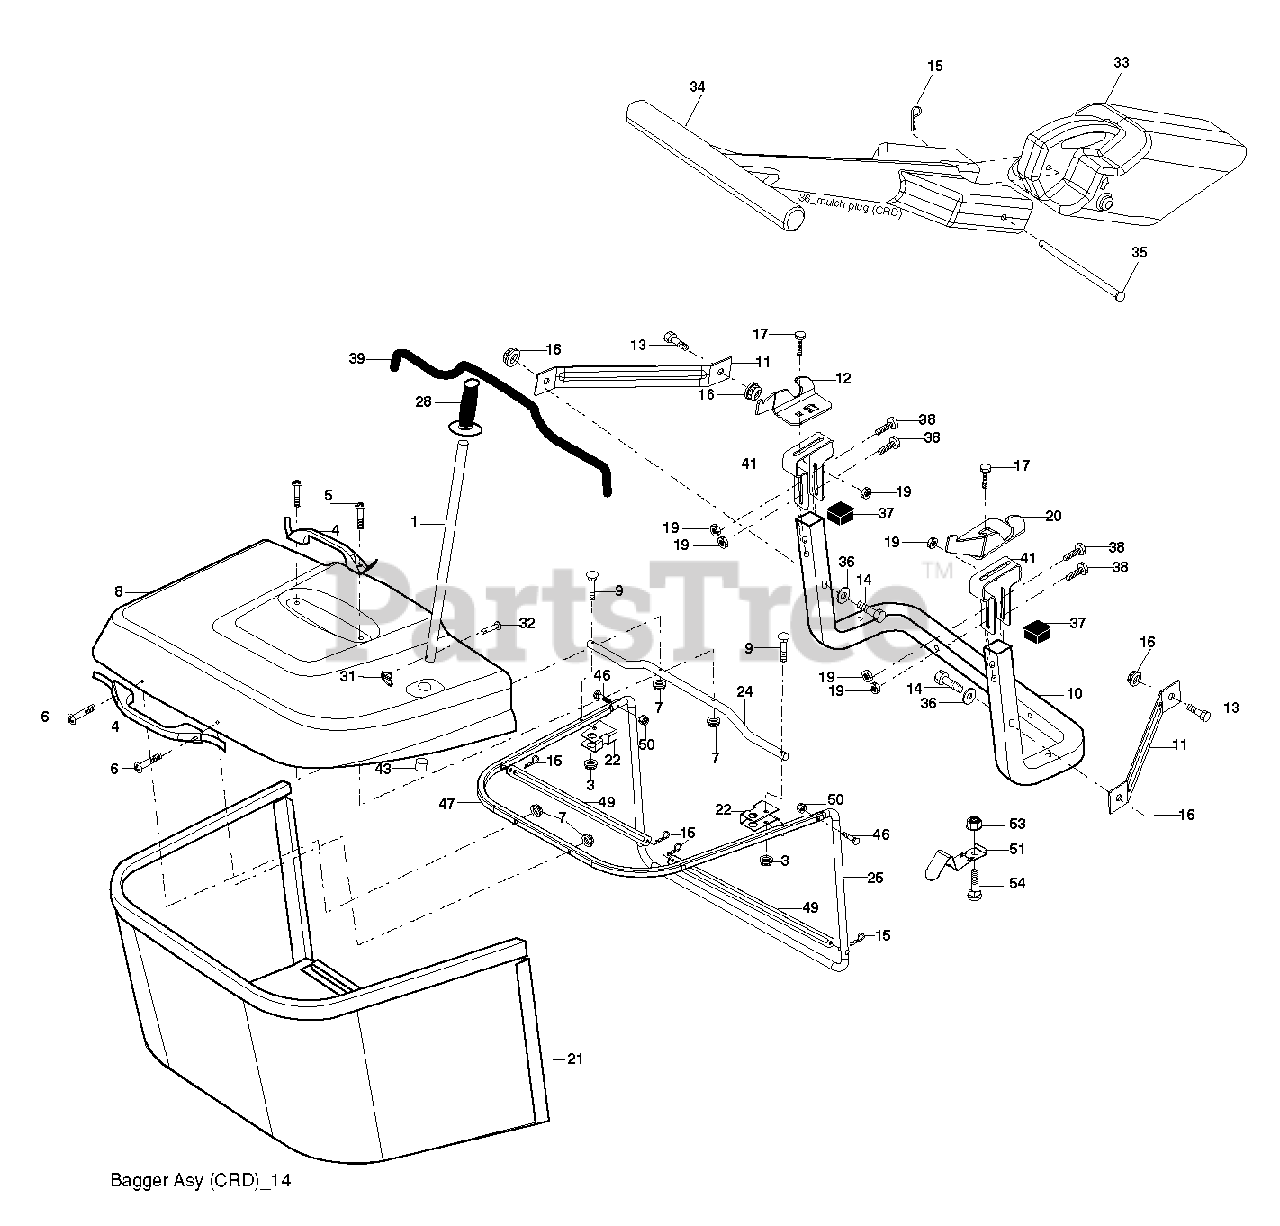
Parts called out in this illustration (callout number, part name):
1	TUBE HANDLE
3	NUT T
5	SCREW.PAN.HEAD
11	BRACKET
14	BOLT-HEX EAK
15	RETAINER-SPRNG RB
16	NUT LOCK FLG 3/8-16 UNC
17	BOLT
19	NUT LOCK HEX FLANGE 5/16-18
20	BRKT.PIVOT.RH.CRD
21	BAGGER.ASM.CRD.2007
22	BRACKET
24	TUBE
28	GRIP.HANDLE.BLACK
31	RETAINER CLIP
32	RIVET,DRILLED
33	PLUG
35	PIN
38	BOLT.5/16-18X2.5
39	SEAL.BAGGER.CRD
41	BRKT, BAGGER
43	PLUG, TUBING END
46	BOLT.CARRIAGE.5/16-18
50	NUT.71038.31-18.HEX.NYLOCK
53	NUT
54	BOLT
